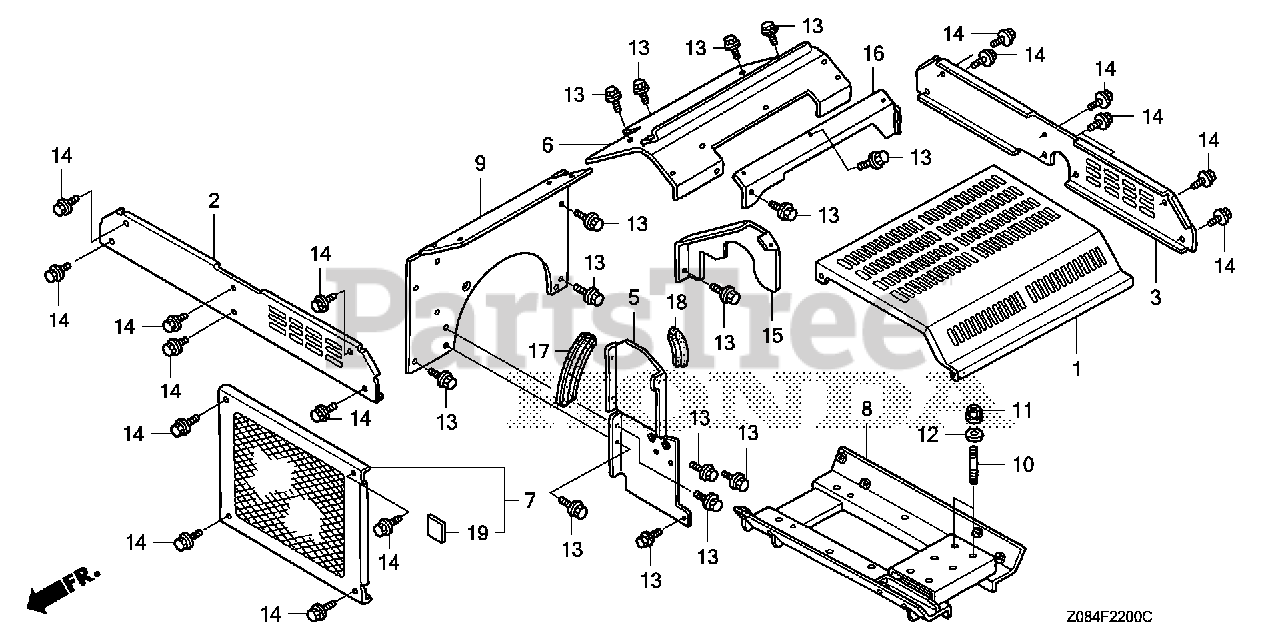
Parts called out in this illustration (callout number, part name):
1	COVER, TOP *R280* (POWER RED)
2	COVER, FR. (UPPER) *R280* (POWER RED)
3	COVER, RR. (UPPER) *R280* (POWER RED)
5	COVER, BATTERY *NH105* (MAT BLACK)
6	COVER, MUFFLER *NH105* (MAT BLACK)
7	COVER, FR. *NH105* (MAT BLACK)
8	BED, ENGINE GENERATOR *NH105* (MAT BLACK)
9	SEPARATOR *NH105* (MAT BLACK)
10	BOLT, STUD (10X45)
11	NUT, FLANGE (10MM)
12	WASHER, PLAIN (10MM)
13	BOLT, FLANGE (6X12)
14	BOLT, FLANGE (6X12)
15	SUB-COVER, MUFFLER *NH105* (MAT BLACK)
16	COVER B, MUFFLER *NH105* (MAT BLACK)
17	SEAL A, SEPARATOR
18	SEAL B, SEPARATOR
19	INSULATOR, BATTERY
